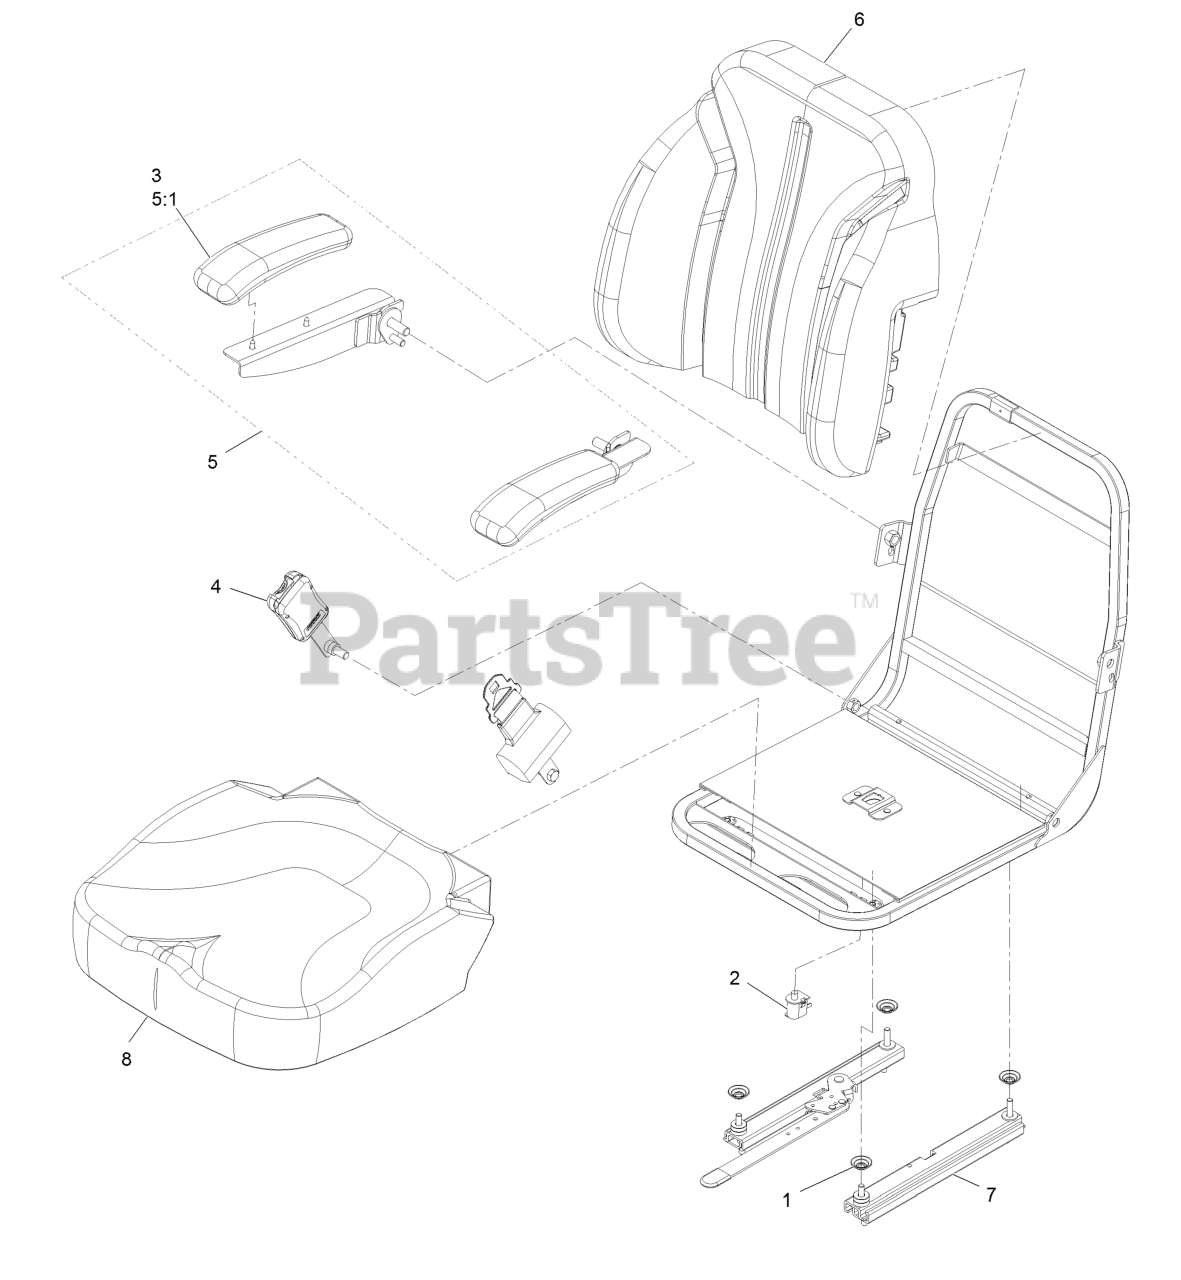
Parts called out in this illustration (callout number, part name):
1	Spacer-Mounting
3	Cushion-Rest, Arm
4	Seat Belt Kit
5	Armrest Kit
5:1	Cushion-Rest, Arm
6	Cover-Seat Back Svc
7	Track-Seat
8	Cover-Seat Bottom Svc
